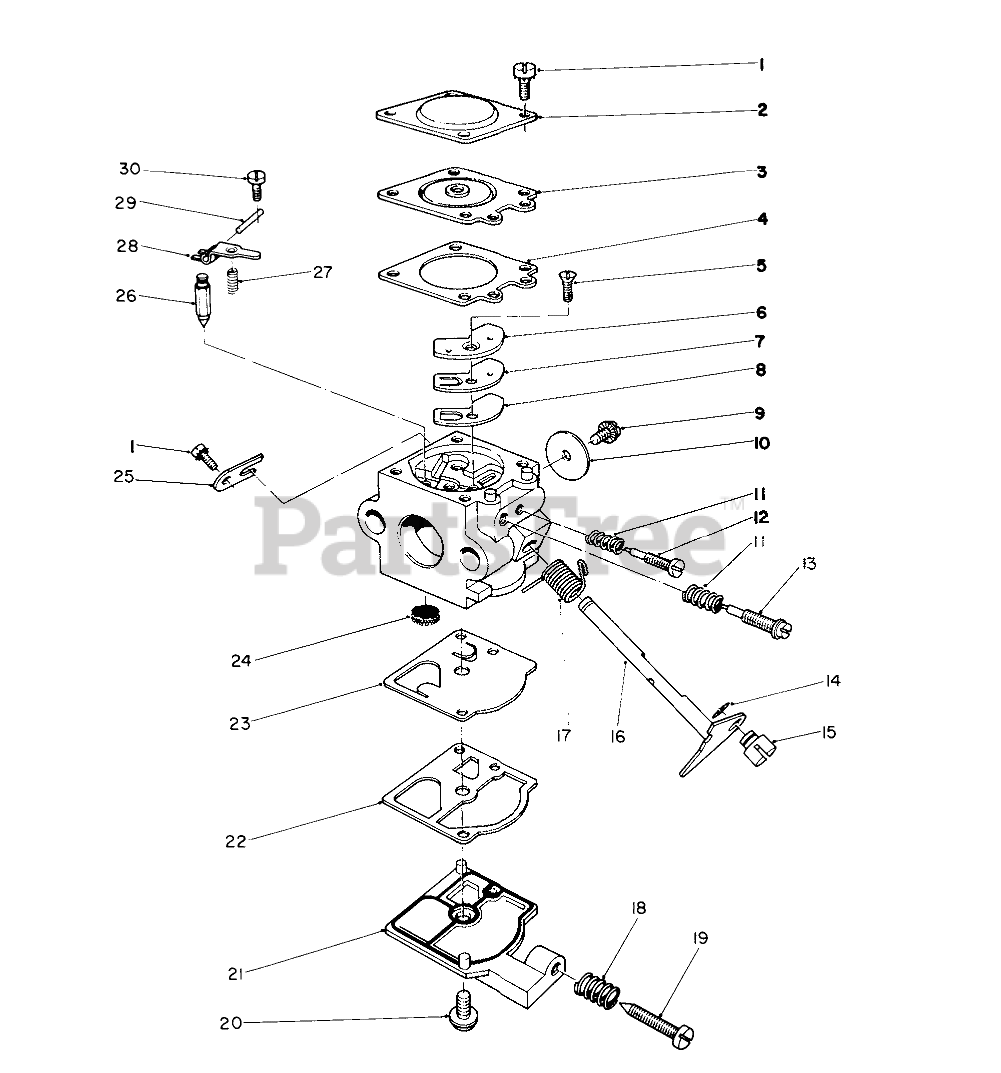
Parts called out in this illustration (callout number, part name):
1	Screw
2	Cover, Diaphragm
3	METERING DIAPHRAGM
4	Gasket, Diaphragm
5	Screw-Circuit Plate
6	Plate, Circuit
7	Diaphragm Circuit Plate
8	Gasket-Circuit Plate
9	Screw
10	Valve, Throttle
11	Spring, Needle
12	Idle Needle
13	High Speed Needle
15	Swivel
16	Throttle Shaft
17	Spring-Throttle Lever
18	Spring, Idle Screw
19	Screw, Idle Adjust
20	Screw
21	Cover, Fuel Pump
22	PUMP GASKET
23	Diaphragm Fuel Pump
24	Screen Inlet
25	Clip Throttle Shaft
26	INLET NEEDLE VALVE
27	Spring, Metering Lever
28	Lever Metering
29	Metering Lever Pin
30	Screw-Metering Pin
